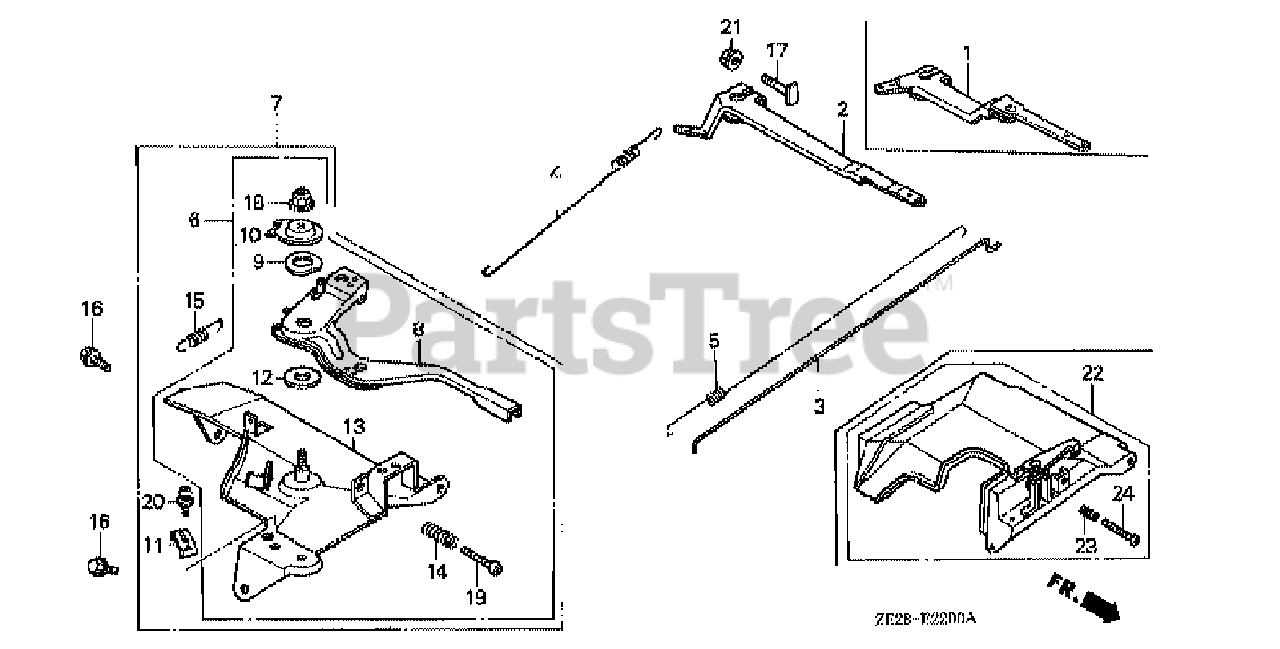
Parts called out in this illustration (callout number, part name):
2	ARM, GOVERNOR
3	ROD, GOVERNOR
4	SPRING, GOVERNOR
5	SPRING, THROTTLE RETURN
7	CONTROL ASSY. (REMOTE)
8	LEVER, CONTROL
9	SPRING, LEVER
10	WASHER, CONTROL LEVER
11	HOLDER, CABLE
12	SPACER, CONTROL LEVER
13	BASE, CONTROL
14	SPRING, CONTROL ADJUSTING
15	SPRING, CABLE RETURN
16	BOLT, FLANGE (6X12) (CT200)
17	BOLT, GOVERNOR ARM
18	NUT, SELF-LOCK (6MM)
19	SCREW, PAN (5X28)
20	SCREW, PAN (5X16)
20	SCREW-WASHER (5X16)
21	NUT, FLANGE (6MM)
